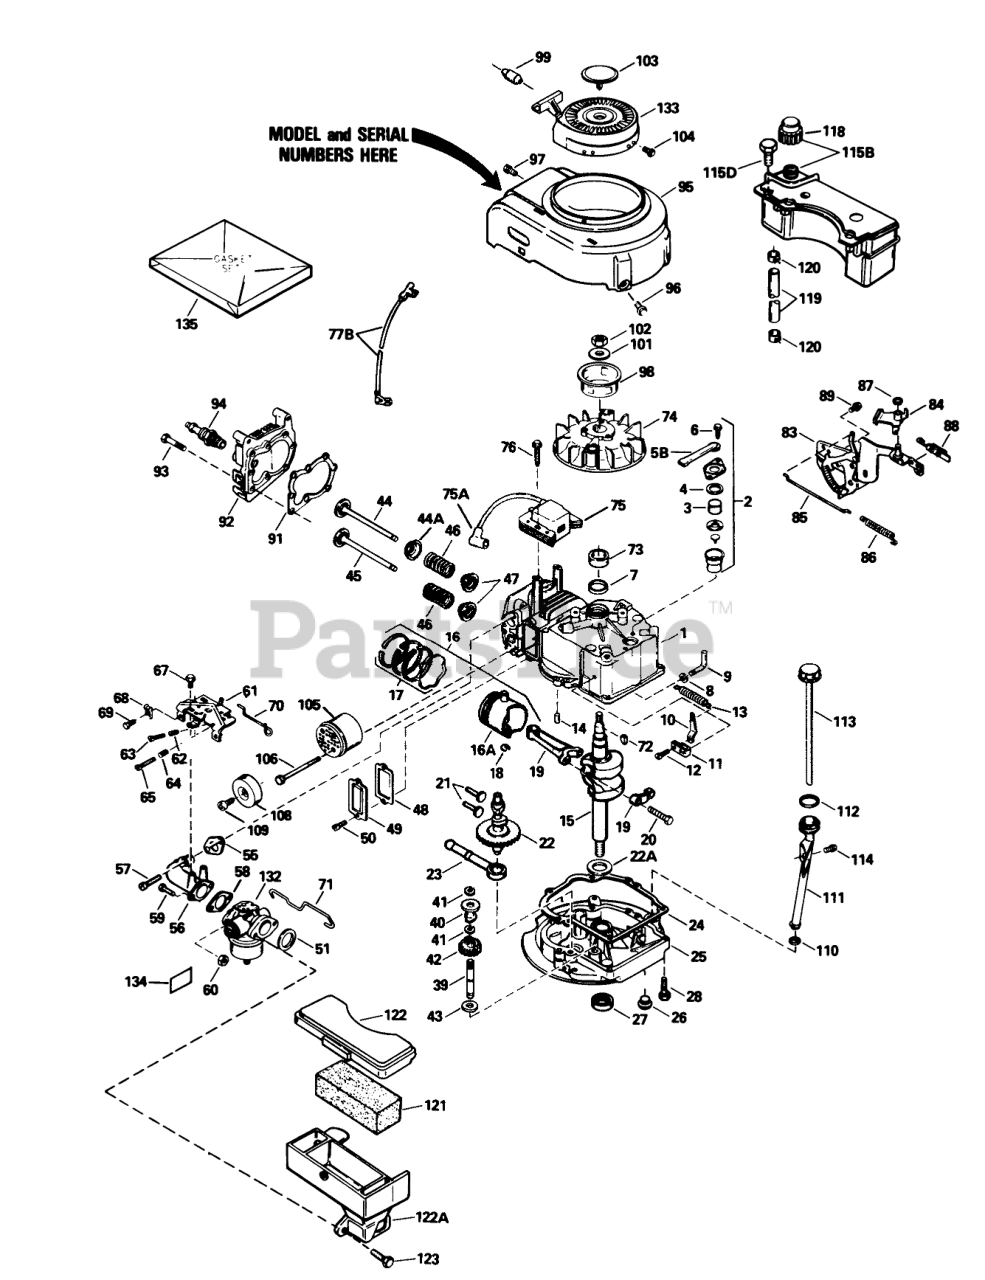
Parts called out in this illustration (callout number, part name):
1	Cylinder Assembly (Incl. Ref. #7 & 14)
2	Breather Assembly (Incl. Ref. #3-6)
3	Element-Breather
4	Gasket-Breather
5B	Tube, Breaker
6	Screw (10-24 x 9/16)
7	Seal-Oil
8	Washer-Flat
9	Rod-Governor (Incl. Ref. #8)
10	Governor Lever
11	Clamp-Lever, Governor
12	Screw
13	Spring Governor
14	Pin-Dowel
15	Crankshaft
16	Piston-Pin & Ring Assy. (Std.)(Incl. Ref. #16A, 17 & 18)
16	Piston-Pin & Ring Assembly (.010 oversize)(Incl. Ref. #16A, 17 & 18)
16	Piston-Pin & Ring Assembly (.020 oversize)(Incl. Ref. #16A, 17 & 18)
16A	Piston & Pin Assembly (Std.)(Incl. Ref. #18)
16A	Piston & Pin Assembly (.010 oversize)(Incl. Ref. #18)
16A	Piston & Pin Assembly (.020 oversize)(Incl. Ref. #18)
17	Ring Set-Piston (Std.)
17	Ring Set, Piston(.0100versize)
17	Ring Set (.020" OS)
18	Ring-Retaining, Piston Pin
19	Rod Assembly-Connecting (Incl. Ref. #20)
20	Bolt-Rod, Connecting
21	Lifter-Valve
22	Camshaft(Mech.Comp. Release)
22A	Washer-Thrust
23	Oil Pump ASM
24	Gasket
25	Flange-Mounting (Incl. Ref. #26, 27 & 39)
26	Plug Oil Drain
27	Seal-Oil
28	Screw (1/4-20 x 1-1/4)
39	Shaft-Governor
40	Spool-Governor
41	Ring-Retaining
42	Gear Assembly-Governor (Incl. Ref. #43)
43	Washer
44	Valve-Intake (Std.)(Incl. Ref. #47)
44	Valve-Intake (1/32" oversize)(Incl. Ref. #47)
44A	Seal Assy., Intake
45	Valve-Exhaust (Std.)(Incl. Ref. #47)
45	Valve-Exhaust (1/32" oversize)(Incl. Ref. #47)
46	Spring-Valve
47	Cap-Valve, Spring
48	Gasket-Cover, Valve
49	Cover-Valve
51	Gasket-Cleaner, Air
55	Gasket-Intake Pipe
56	Pipe-Intake (Incl. Ref. #55)
57	Screw (1/4-20 x 1)
59	Screw (1/4-28 x 7/8)
60	Nut and Lock Washer (1/4-28)
61	Bracket Assembly-Control (Incl. Ref. #62-65)
62	61709/GIL1515A/95-5
63	Screw
64	Spring-Compression
65	Screw
67	Screw (10-24 x 9/16)
68	Conduit
69	Screw (10-32 x 3/8)
70	2035A67 ADD.ASSEMBL
71	Link-Throttle
72	Key-Flywheel
74	Flywheel
75	Solid State
75A	Cover-Spark Plug
76	Screw
77B	Ground Wire
83	Bracket-S.E. Brake
84	Lever-Brake
85	Link-Control
86	Spring-Extension
87	Ring-Retaining
88	Terminal
89	Screw (1/4-20 x 3/8)
91	Gasket-Cylinder Head
92	Head-Cylinder
93	Screw (5/16-18x1-1/2)
94	Spark Plug-Resistor (R J19 L M)
95	Housing-Blower
96	Screw (1/4-20 x 1/2)
97	Screw (10-24 x 9/16)
98	Hub-Starter
99	Retainer-Starter Rope
101	Washer-Belleville
102	Nut-Flywheel
103	Plug Starter
104	Screw, Hex Hd.
105	Muffler Assembly (Incl. Ref. #106)
108	Cover-Muffler
109	Screw (8-32 x 3/8)
111	Oil Fill Tube
113	Dipstick
114	Screw (10-32 x 1/2)
115B	Tank Assembly (Incl. Ref. #118 & 120)
115D	Screw (10-32 x 35/64)
118	Cap-Fuel
119	Line-Fuel
120	Clamp-Line, Fuel
121	Filter-Air Cleaner
122	Cover-Air Cleaner
122A	Body Air cleaner
132	Carburetor (Incl. Ref. #58)
133	Starter-Rewind
134	Decal-Primer
135	Gasket Set (Incl. Items Marked )
